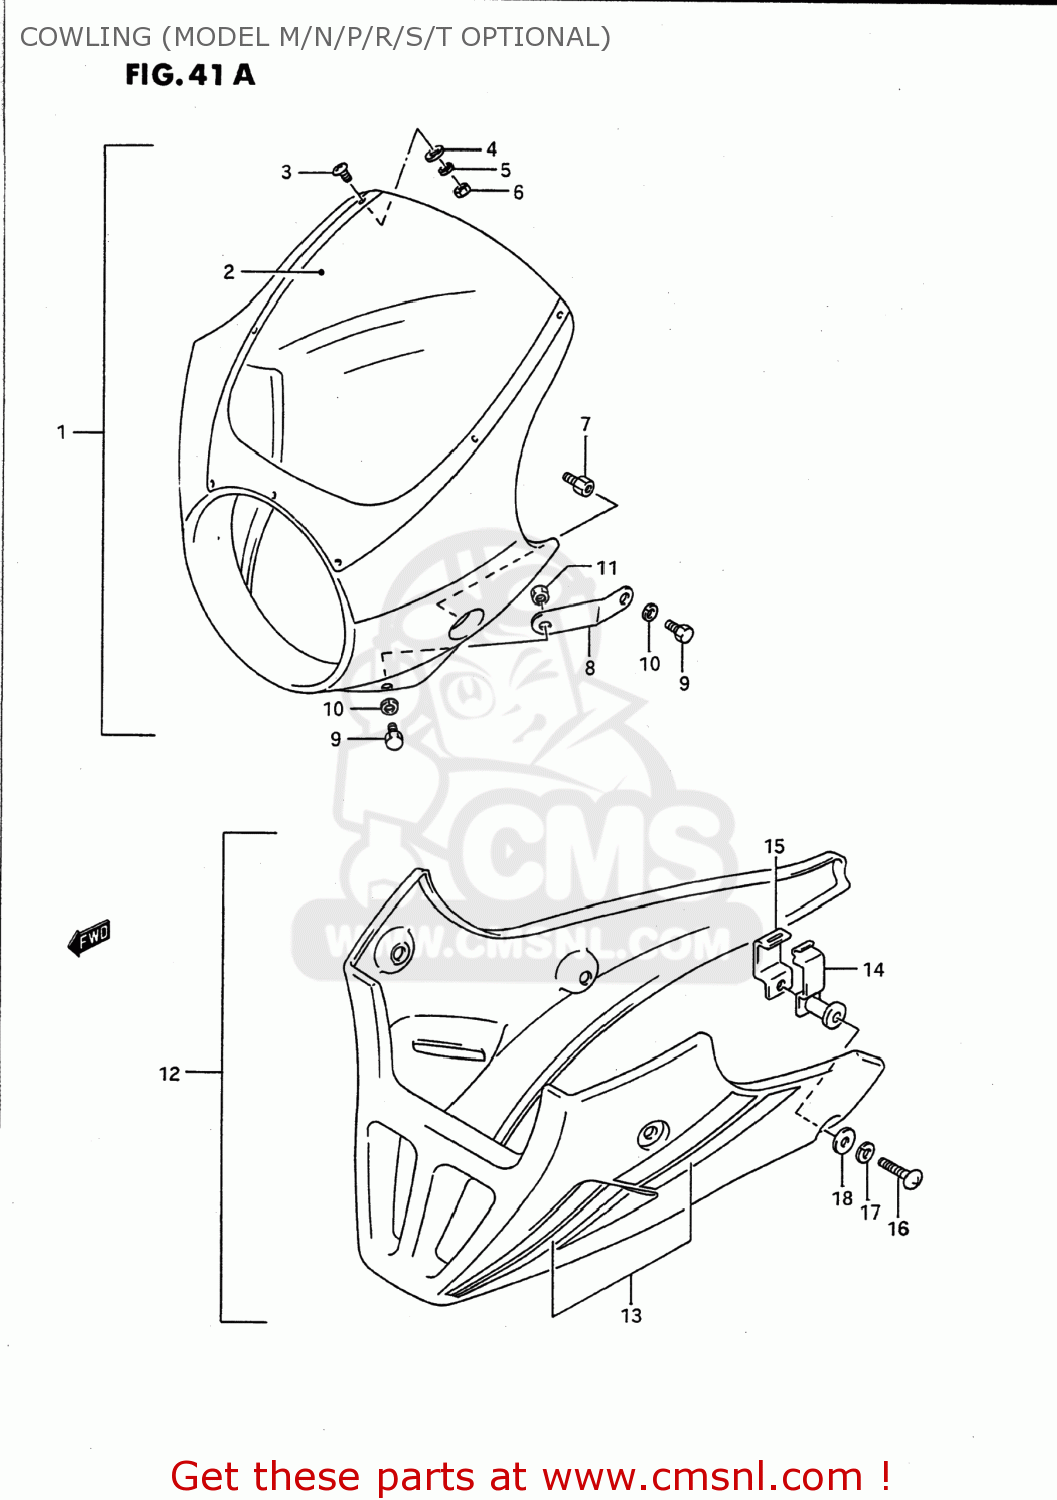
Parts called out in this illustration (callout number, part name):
1	COVER SET,UPPER COWLING
2	SCREEN,COWLING
3	SCREW
4	WASHER
5	LOCK WAHSER
6	NUT
7	BOLT,UPR COWLING HEADLAMP
8	BRACE,UPR COWLING
9	BOLT
10	WASHER,LOCK
11	NUT 6MM
12	COVER SET,UNDER COWLING
13	TAPE SET,UNDER COWLING
14	BRACKET,UNDER COWLING OUTER
15	BRACKET,UNDER COWLING INNER
16	SCREW
17	WASHER,LOCK
18	WASHER
